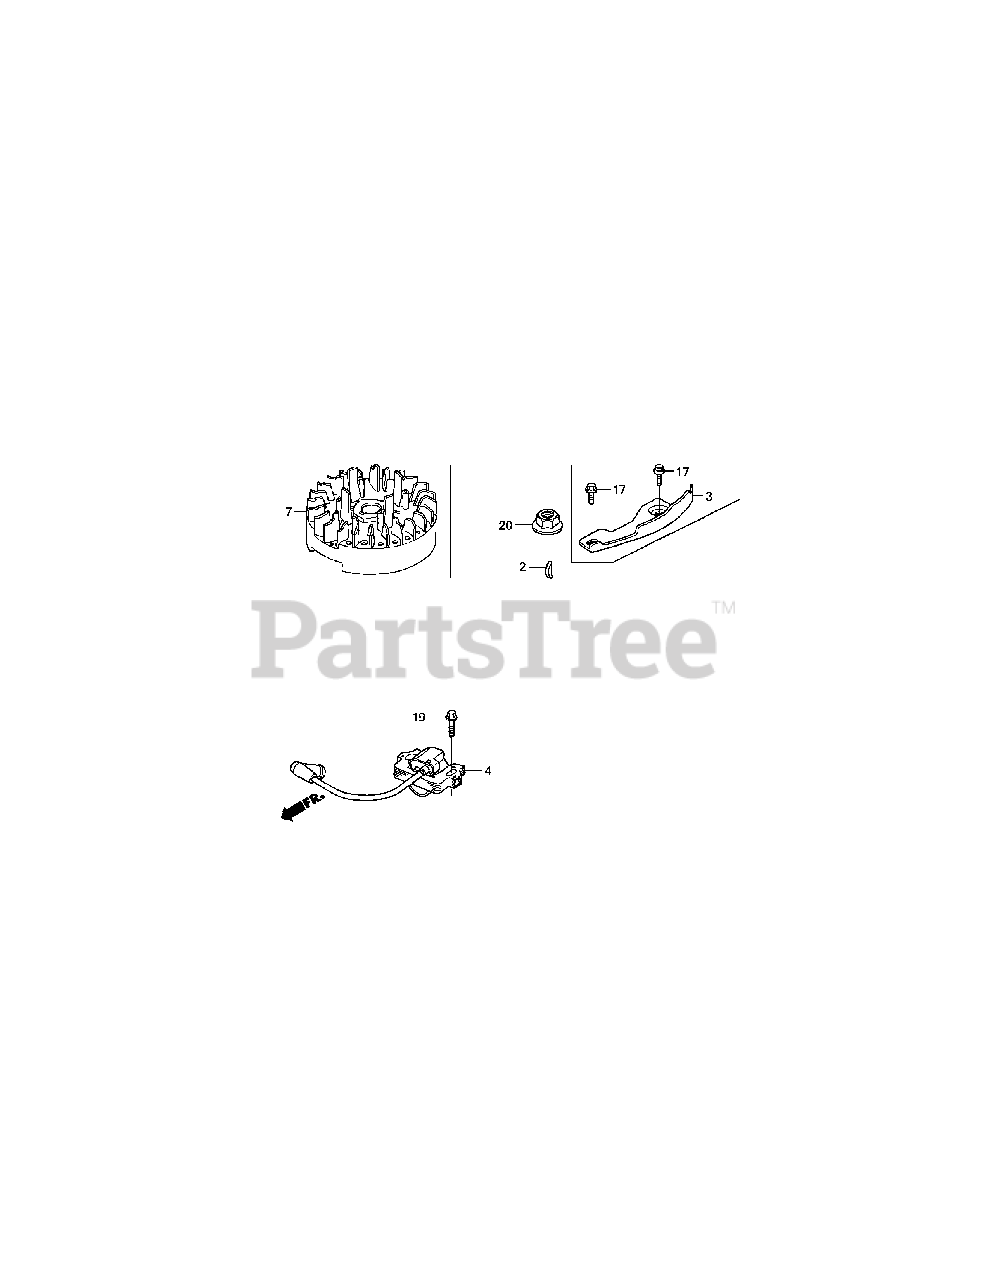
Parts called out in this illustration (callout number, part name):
2	Woodruff Key
3	Side Plate
4	Ignition Coil Assembly
7	Complete Flywheel
17	Flange Bolt, 6 x 12
19	Flange Bolt, 6 x 20
